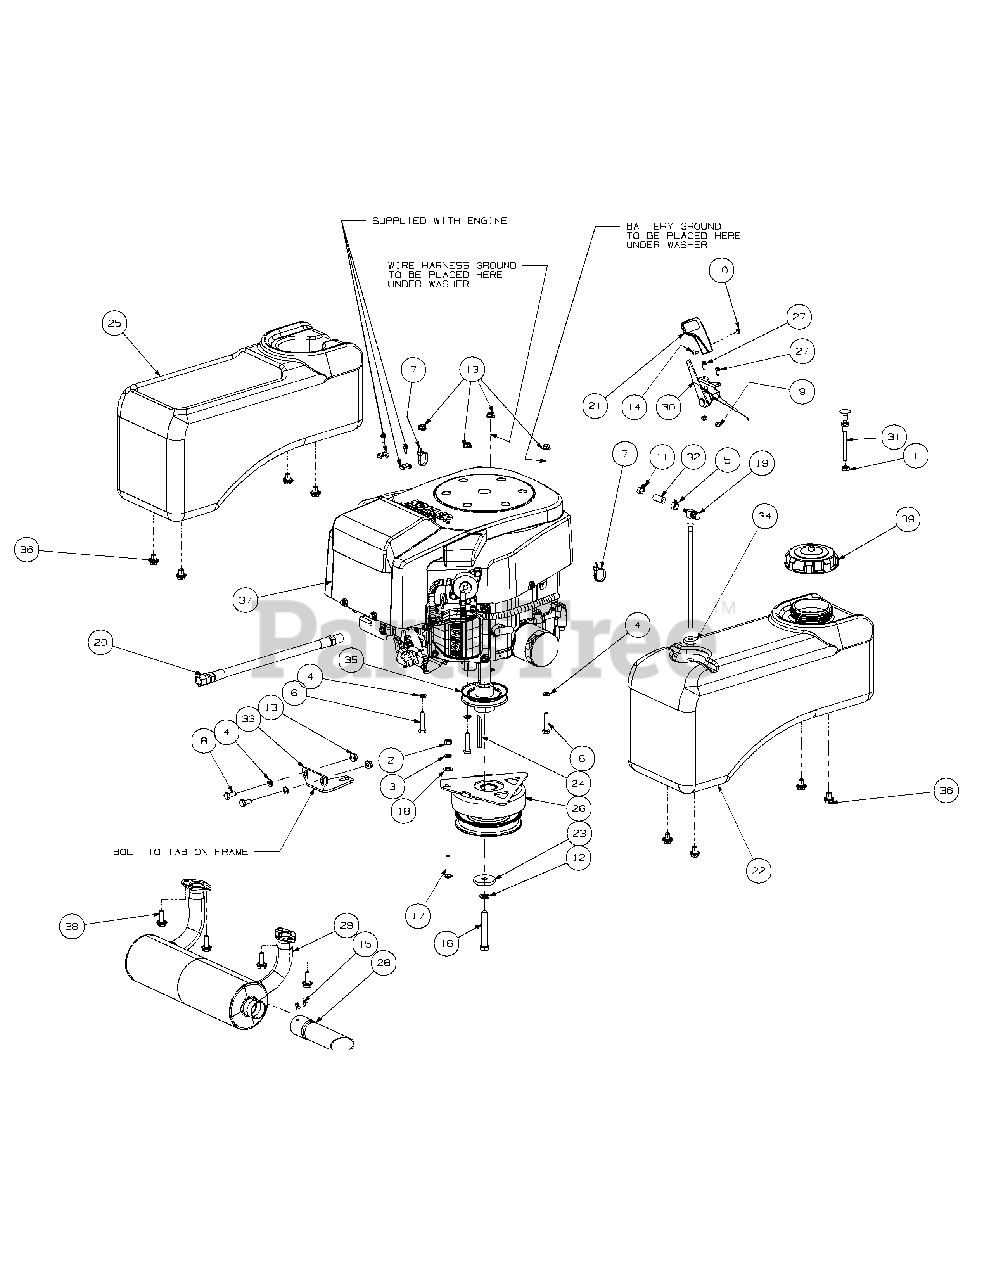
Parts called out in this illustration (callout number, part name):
1	Hex Jam Nut, 3/8-24
2	Hex Nut, 5/16-18
3	Lock Washer, 5/16
4	Flat Washer, 5/16
5	Clamp, Union
6	Hex Cap Screw, 3/8-16 x .875
7	Cable Tie, 3/16 x .05 x 7.4
8	Hex Cap Screw, 5/16-18 x .75
9	Lock Nut, Nylon Insert, 10-32
10	Nut, w/ Star Washer
11	Hose Clamp, 1/4-5/8, SS
12	Lock Washer, 7/16
13	Lock Nut, Hex Flange, 5/16-18
14	Machine Screw, 8-32 x .375
15	Screw, 8-32 x .375, Hex Washer
16	Hex Cap Screw, 7/16-20 x 3.0
17	Carriage Bolt, 5/16-18 x 1.75
18	Washer, 3/8 x .738 x .063
19	Fuel Pickup Fitting
20	Oil Drain Extension Hose
21	Throttle Control Knob
22	Fuel Tank
23	Flat Washer, 7/16 ID x 1.75 OD x .250
24	Key, 1/4 x 1/4 x 2.75
25	Utility Bin
26	Ogura DX11 Electric Clutch
27	Screw, #10-32 x 0.500
28	Exhaust Pipe
29	Kohler Muffler
30	Throttle Control Cable
31	Choke Cable
32	Hose, 1/4" Fuel Line
34	Fuel Tank Groment
35	Transmission Drive Pulley
36	Hex Head Cap Screw, 3/8-16 x 1.00, Flange Whiz
37	20HP Kohler Engine
38	Hex Head Cap Screw, 5/16-18 x 1.00, Flange Whiz
39	Fuel Cap
